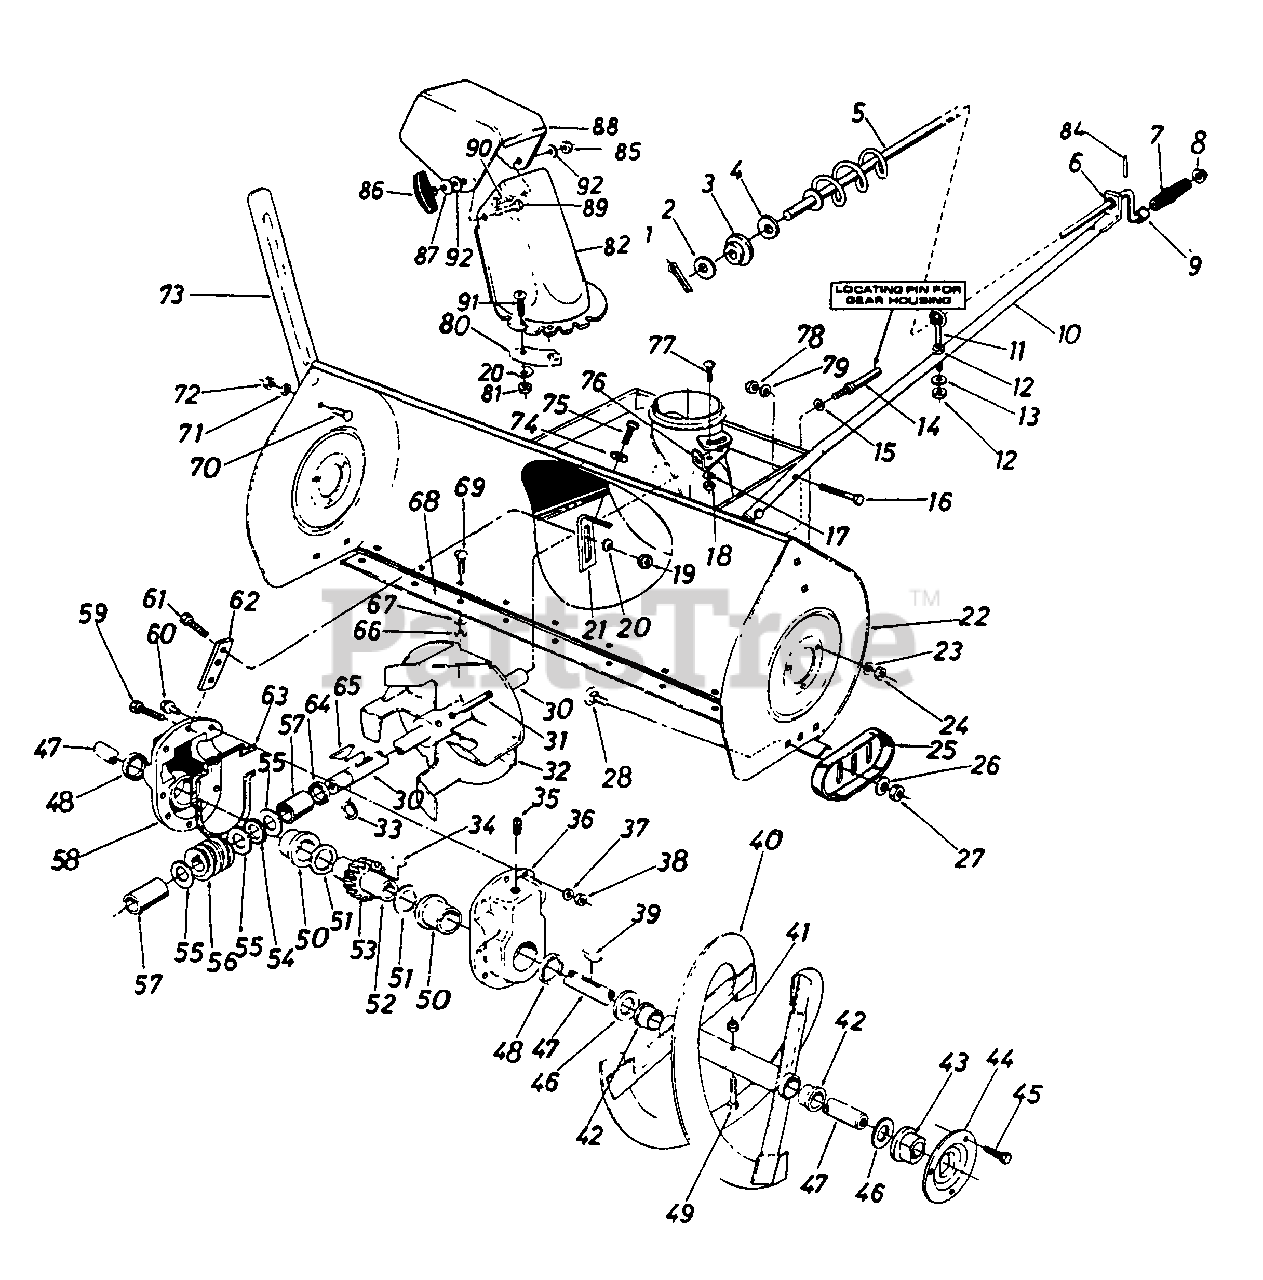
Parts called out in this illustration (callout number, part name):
1	Cotter Pin
2	Fl-Wash. .39" I.D. x .62" O.D.
3	Plastic Bushing
4	Fl-Wash. .385" I.D. x .62" O.D.
5	Chute Crank Ass'y.
6	Plastic Bushing
7	Knob (Black)
8	Push Nut 3/8" Rod
9	Spacer. .385" I.D. x .50" O.D.
10	Chute Crank Support Tubing
11	Eyebolt
12	Hex Nut 5/16-18 Thd.
13	Bell-Wash. .345" I.D. x .88" O.D.
14	Stud 3/8-16 x 2.75" Lg.
15	Bell-Wash. .400" I.D. x .88" O.D.
16	Hex Bolt 3/8-24 x 1.25" Lg.
17	Bell-Wash. .345" I.D. x .88" O.D.
18	Hex Nut 5/16-18 Thd.
19	Hex Nut 1/4-28 Thd.
20	Bell-Wash. .265" I.D. x .75" O.D.
22	45" Snow Blower Housing Ass'y.
23	L-Wash. 5/16" I.D.
24	Hex Nut 5/16-18 Thd.
25	Slide Shoe
26	Bell-Wash. .400" I.D. x .88" O.D.
27	Hex Jam Nut 3/8-16 Thd.
28	Carriage Bolt 3/8-16 x .62" Lg.
30	Blower Axle .875" Dia. x 14.75" Lg.
31	Spring Pin Spir. 5/16" Dia. x 1.75" Lg.
34	#91 Woodr-Key 1/4 x 3/4" Dia. (Hdn.)
35	Vent Plug
36	Comp. Gear Hsg. Half - L.H.
37	Spr.- Wash. .32" I.D. x .62" O.D.
38	Hex Ins. L-Nut 5/16-18 Thd.
39	#91 Woodr-Key 1/4 x 3/4" Dia. (Hdn.)
41	Hex Ins. L-Nut 5/16-18 Thd.
42	Plastic Bushing
43	Flange Brg. w/flats 1" I.D.
44	Bearing Housing
45	Hex Sems Bolt 5/16-18 x .75" Lg.
46	Fl-Wash. 1.00" I.D. x 1.75" O.D.
47	Spiral Axle
48	Flange Bearing 1.503" I.D.
49	Shear Bolt 5/16-18 x 1.75" Lg.
50	Oil Seal 1.50" I.D.
51	Fl-Wash. 1.50" I.D. x 2.00" O.D.
52	Worm Gear Shaft
53	Double Threaded Worm Gear - L H.
54	Thrust Brg.- .88" I.D. x 1.44" O.D.
55	Fl-Wash. .88" I.D. x 1.4" O.D.
56	Double Threaded Worm - L.H.
57	Sleeve
58	Complete Gear Hsg. Half - R.H.
59	Hex Bolt 5/16-18 x 1.25" Lg.
60	Hex Bolt 5/16-18 x 1.0" Lg. (Gr. 5)
61	Hex Bolt 1/4-28 x .75" Lg.
62	Gear Housing Support Plate
63	Rubber Gasket
64	Oil Seal -.875" I.D.
65	#9 Hi-Pro Key 3/16 x 3/4" Dia.
66	Hex Nut 5/16-18 Thd.
67	L-Wash. 5/16" I.D.
69	Carriage Bolt 5/16-18 x 1.00" Lg.
70	Carriage Bolt 5/16-18 x .62" Lg.
71	L-Wash. 5/16" I.D.
72	Hex Nut 5/16-18 Thd.
73	Guide Blade
74	Bell-Wash. .345" I.D. x .88" O.D.
75	Hex Wash. Hd. AB-Tap Scr. 5/16 x .75" Lg.
77	Carriage Bolt 5/16-18 x .75" Lg.
78	Hex Ins. L-Nut 3/8-24 Thd.
79	L-Wash. 3/8" I.D.
80	Chute Flange Keeper
81	Hex Nut 1/4-20 Thd.
82	Chute Ass'y. w/Chute Guard
84	Bell-Wash. .345" I.D. x .88" O.D.
85	Hex Cent. L-Nut 5/16-18 Thd.
86	Knob Handle
87	Bell-Wash. .345" I.D. x .88" O.D.
88	Top Chute Ass'y.
89	Carriage Bolt 5/16-18 x 1.00" Lg.
90	Carriage Bolt 5/26-18 x .62" Lg.
91	Truss Mach. Scr. 1/4-20 x .75"
92	Roll Pin .12 Dia. x .63"
